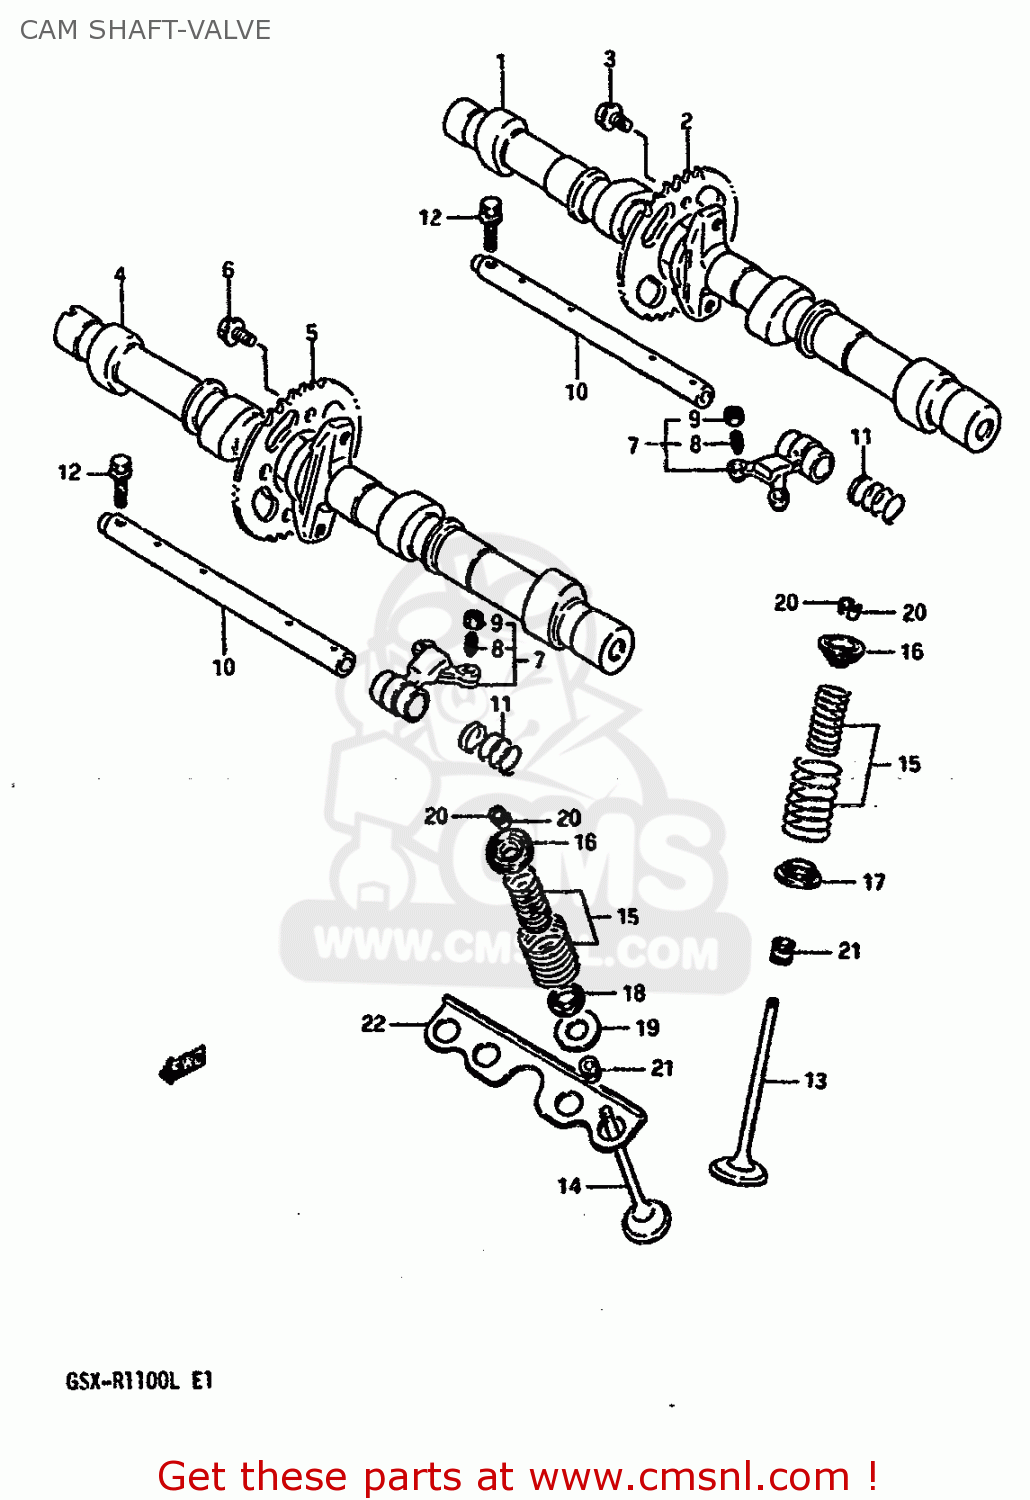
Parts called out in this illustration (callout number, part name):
1	CAMSHAFT
2	SPROCKET,CAMSHAFT
3	BOLT(7X11)
4	CAMSHAFT,EXHAUST
5	SPROCKET,CAMSHAFT
6	BOLT(7X11)
7	ARM,VALVE ROCKER
8	SCREW,TAPPET ADJUSTING
9	NUT,ADJUSTING
10	SHAFT,VALVE ROCKER ARM
11	SPRING
12	BOLT
13	VALVE,INTAKE
14	VALVE,EXHAUST
15	SPRING SET,VALVE
16	RETAINER,VALVE SPRING
17	SEAT,VALVE SPRING
18	SEAT,VALVE SPRING
19	SEAT,VALVE SPRING EXH OUTER
20	COTTER VALVE
21	SEAL,OIL(5X10X9.7)
22	PLATE
